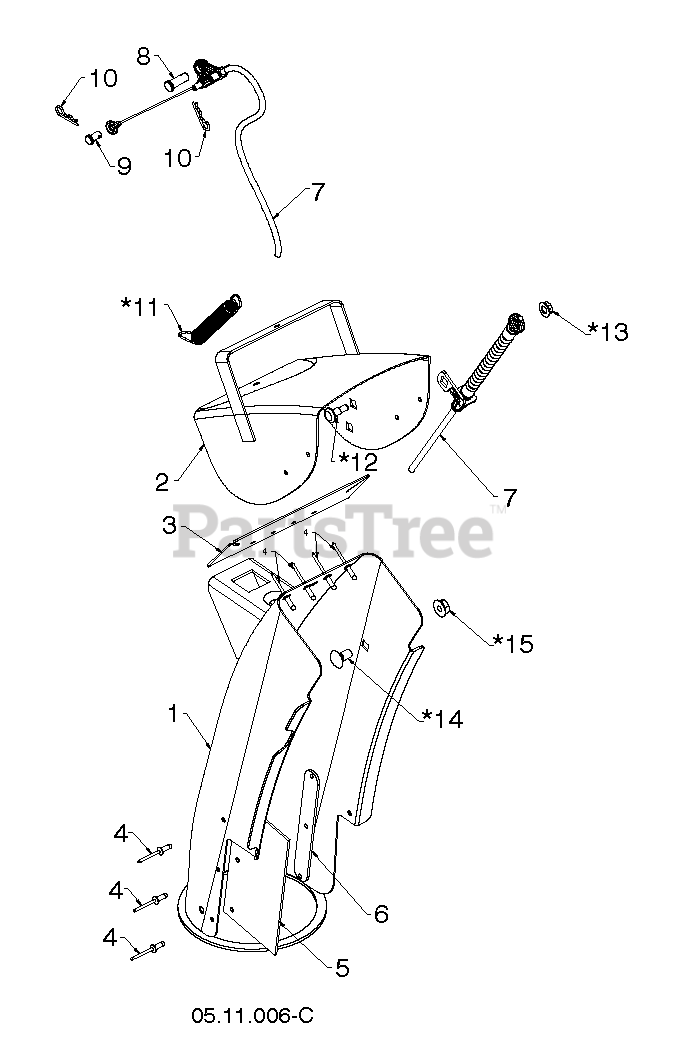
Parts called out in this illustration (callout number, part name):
1	RP_CHUTE.WELDMENT.SNOW.ORANGE
2	DEFLECTOR.WELDMENT.PNT.ORANGE
3	SEAL.DEFLECTOR
4	RIVET BLIND
5	SHIELD.SNOW.CHUTE
6	STRAP.SHEILD.RETAINER
7	CABLE CONTROL.CHUTE.DEFL.BOWDE
8	PIN CLEVIS 5/16X.875
9	PIN CLEVIS .25 X .31
10	HAIRPIN.SOFT.ZINC.059X1.125
11	SPRING.DEFLECTOR.REM.CHUTE
12	BOLT SHOULDER 1/4
13	NUT.HEX.LRG.FLANGE.1/4-20.LOCK
14	BOLT CAR BLK 5/16-18 X 5/8
15	NUT.HEX.FLANGE.LOCK.5/16-18
